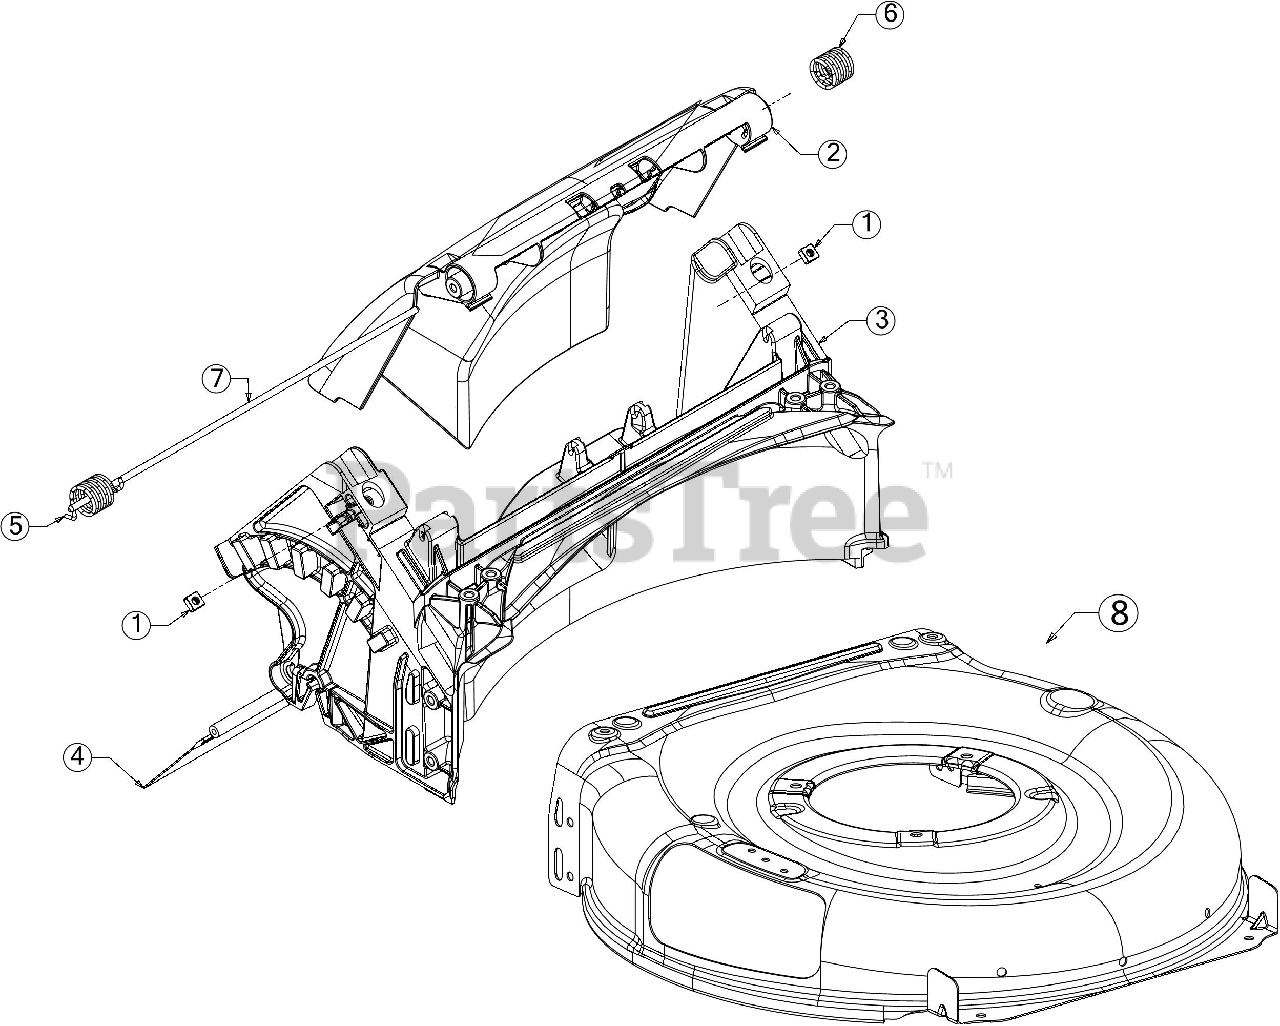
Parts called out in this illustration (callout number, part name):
1	SQUARE NUT 1/4-20
3	DOOR ASSEMBLY
4	TRAILSHIELD
5	TORSION SPRING (RH)
6	TORSION SPRING (LH)
7	REAR DOOR PIVOT ROD
8	21" DECK (3N1)
